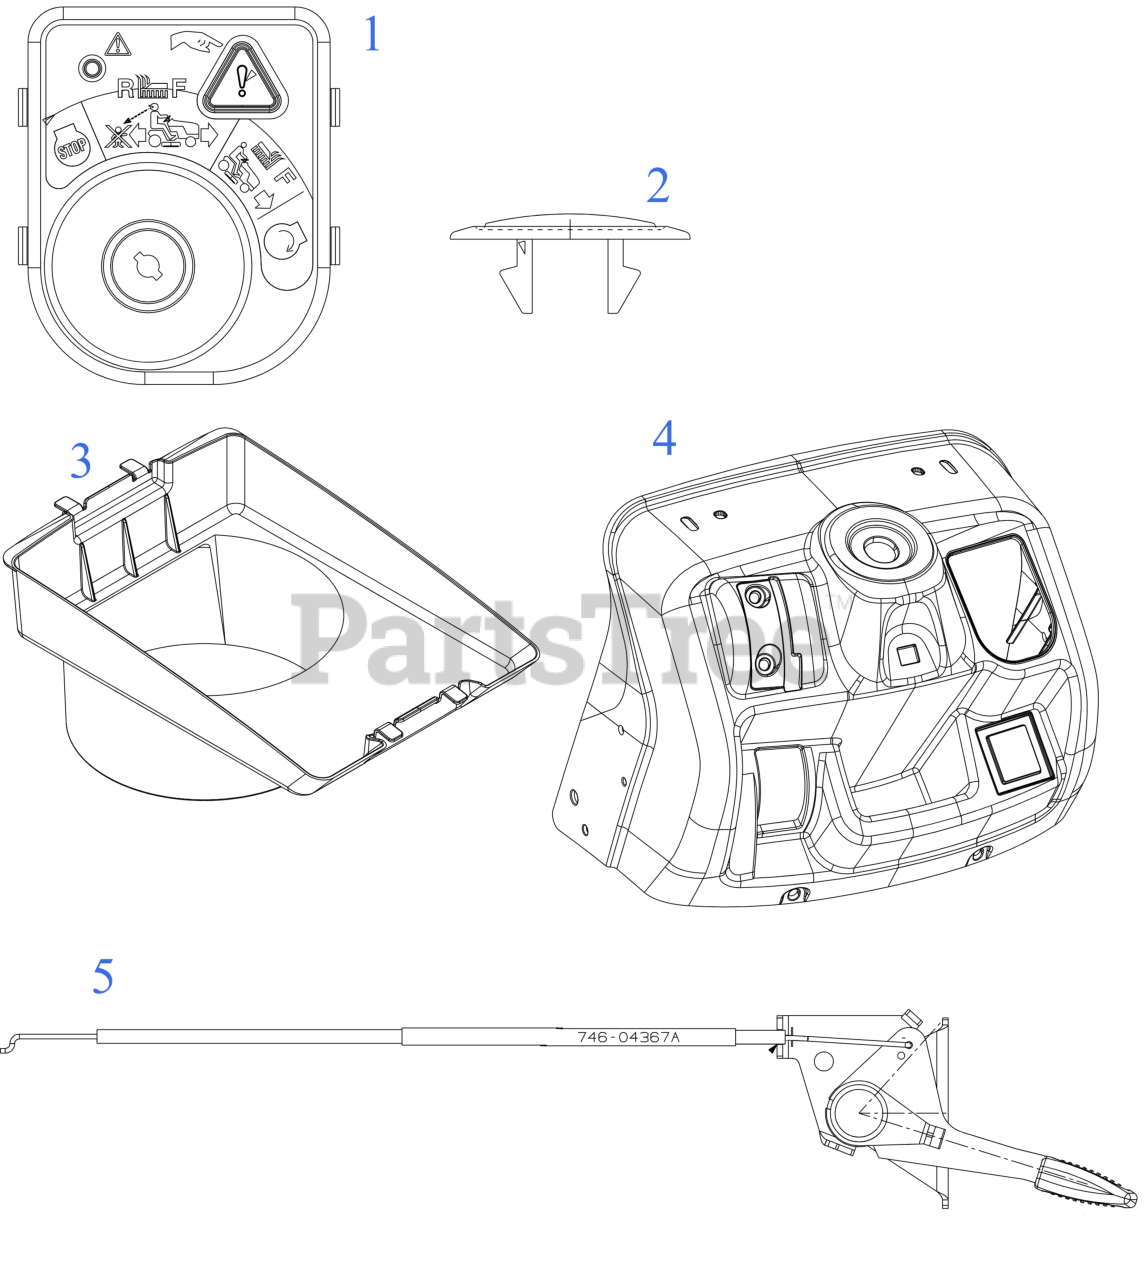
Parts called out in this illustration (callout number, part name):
1	IGNITION MODULE SWITCH RMC (MAN PTO BLK)
2	CHOKE PLUG
3	HOOD PLENUM
4	UPPER DASH
5	THROTTLE CABLE 28" x 1.1
